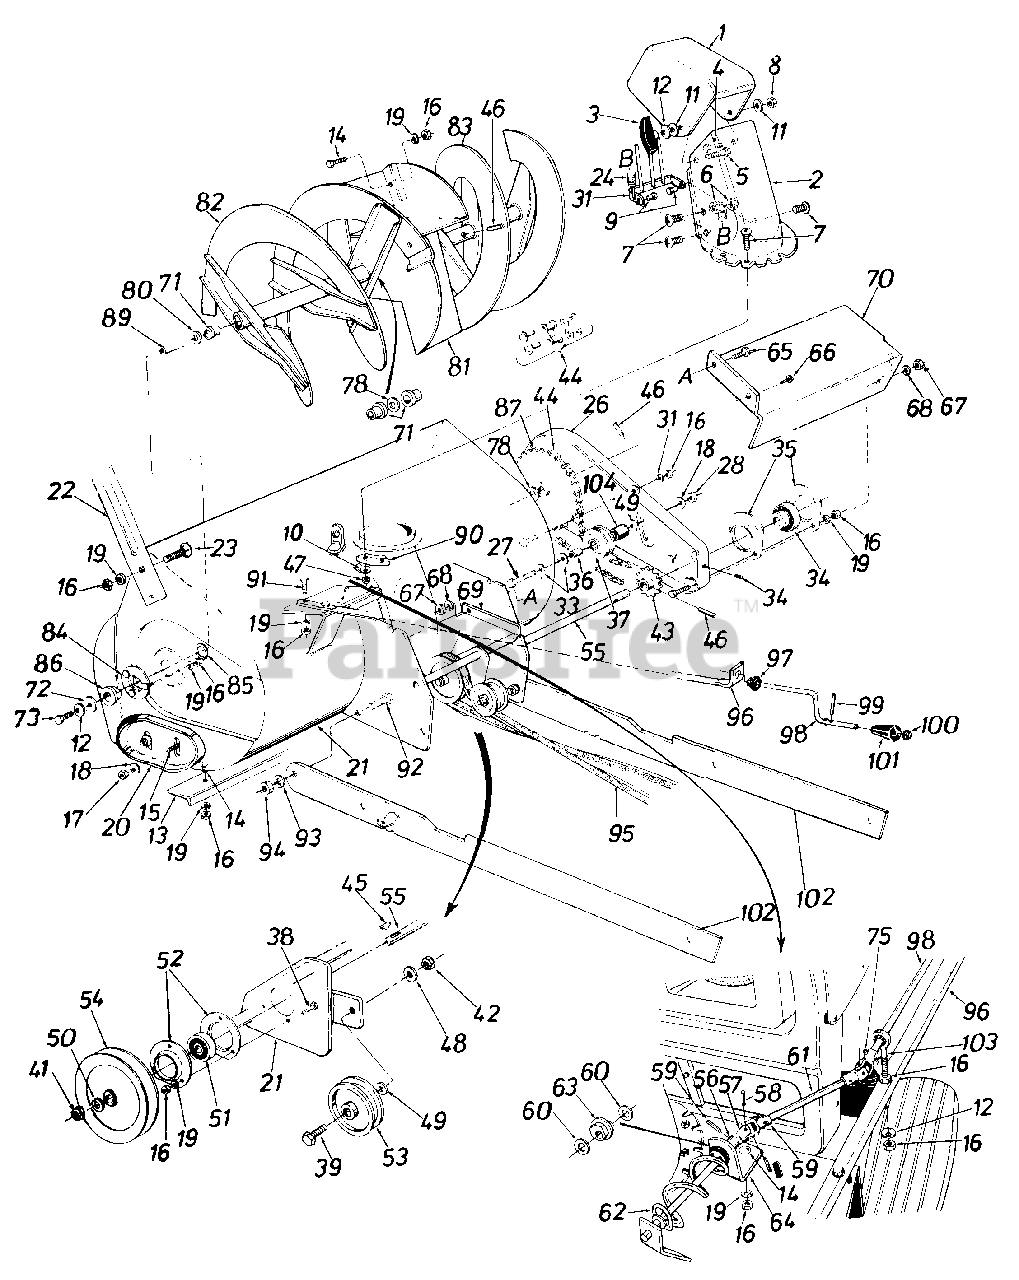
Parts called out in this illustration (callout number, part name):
1	Upper Chute
2	Lower Chute
3	Knob Handle Ass'y.
4	Truss Mach. Scr. 5/16-18 x .75" Lg.
5	Carriage Bolt 5/16-18 x 1.0"
6	Hex Cent. L-Nut 5/16-18 Thd.
7	Truss Mach. Scr. 1/4-20 x .75" Lg.
8	Hex Cent. L-Nut 5/16-18 Thd.
9	Shld. Nut 1/4-20 Thd.
10	Fl. Wash. 1/4" I.D.
11	Fl.-Wash. .344" I.D. x 1.125"
12	Bell. Wash. .345" I.D. x .88"
14	Carriage Bolt 5/16-18 x .62"
15	Carriage Bolt 3/8-16 x .62"
16	Hex Nut 5/16-18 Thd.
17	Hex Jam Nut 3/8-16 Thd.
18	Bell. Wash. .40 I.D. x .88"
19	L.-Wash. 5/16" I.D.
20	Slide Shoe
21	Spiral Hsg. Ass'y.-36"
22	Guide Blade
23	Carriage Bolt 5/16-18 x .62"
24	Extension Spring
26	Chain Guard Ass'y.
27	Hex Bolt 3/8-16 x 2.00 Lg.
28	Hex Inst.-Nut 3/8-16 Thd.
33	Fl.-Wash. .385" I.D. x .87" 0. D.
34	Ball Brg. .75" I.D.
35	Flangette
36	Spacer .375" I.D. x .60" O.D.
37	Fl.-Idler w/Flanges 1.875
38	Hex Sems Bolt 5/18x.75" Lg.
39	Hex Bolt 3/8-16 x 1.75" Lg.
41	Hex Jam Nut 3/4-10 Thd.
42	Hex Jam Nut 3/8-16 Thd.
43	Sprocket Ass'y. 14 Teeth
44	#420 Chain x 1/2" Pitch 77 Links
45	#61 Hi-Pro-Key 3/16 x 5/8"
46	Spring Pin Spir. 5/16" Dia. x 1.75" Lg.
47	Hex L-Nut 1/4-20 Thd.
48	L.-Wash. 3/8" I.D.
49	Fl.-Wash. .406" I.D. x 1.25"
50	Spring L.-Wash. 3/4" I.D.
51	Self-Aligning Brg.
52	Flangette
53	Idler Pulley
54	5/8 V Pulley .75" I.D. x 6"
55	Drive Shaft Ass'y
56	Joint Brkt. Ass'y.
57	Joint Block
58	Oval Head Rivet
59	Spiral Pin 1/8" Dia.
60	Fl. Wash. .385" I.D. x .62"
61	Chute Crank Ext. Rod
62	Chute Crank Ass'y. R.H.
63	Plastic Bushing .380" I.D.
64	Chute Crank Brkt.
65	Hex Bolt 1/4-20 x .62" Lg.
66	Hex Wash. S-Tap Scr. 1/4 2G x .50" Lg.
67	Hex Nut 1/4-20 Thd.
68	L.-Wash. 1/4" I.D.
69	Belt Cover
70	Drive Shaft Cover
71	Plastic Bushing
72	Washer .39" I.D. x 1.75" O.D.
73	Hex Bolt 5/16-18 x .88" Spec
75	Cotter Pin 3/32" Dia.
78	Fl.-Wash. 1.03" I.D. x 1.62"
80	Fl.-Wash. 1.0" x 1.75"
85	Snap Ring for 1.50" Shaft
86	Flange Brg. w/flats 1.00" I.D.
87	Sprocket Hub Ass.y. 40 Teeth
89	Spiral Axle
90	Chute Flange Keeper
91	Hex Bolt 5/16-18 x 1.5" Lg.
92	Hex Bolt 1/2-13 x 1.25" Lg.
93	L.-Wash. 1/2" I.D.
94	Hex Nut 1/2"-13 Thd.
95	"V"Belt
98	Chute Crank 34.5" L.g
99	Roll Pin .12 Dia. x .63
100	Push Nut 3/8" Rod
101	Knob Black
102	Linkage Arm
103	Eye Bolt 5/16-18 x 3.0" Lg.
104	Idler Spacer
